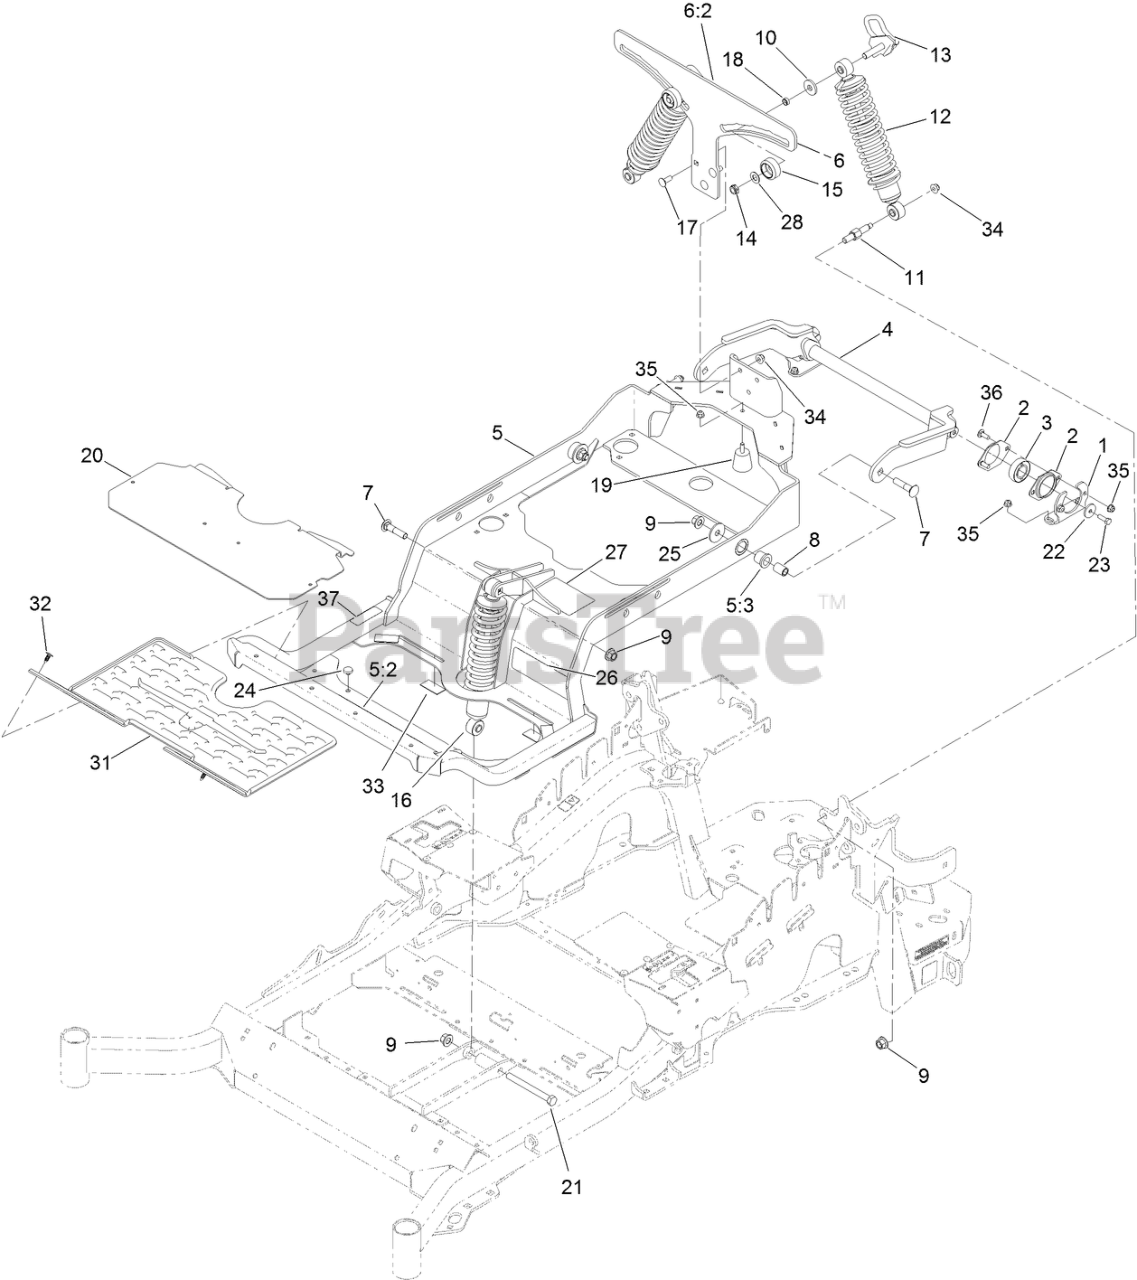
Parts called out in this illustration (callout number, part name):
1	BRACKET-BEARING
2	HOUSING-BEARING, FLANGE
3	BEARING
4	ARM-TRAILING
5	SUBFRAME ASM
5:2	DECAL-DANGER
5:3	BUSHING-FLANGE
6	BRACKET-MOUNTING
6:2	DECAL-ADJUSTMENT, RIDE
7	SCREW-CARR
8	SPACER-ALUMINUM
9	NUT-LOCK
10	WASHER-PLASTIC
11	BOLT-SHOULDER
12	SHOCK/SPRING ASM
13	CAM LOCK ASM
14	NUT-HEX
15	KNOB-LOCK, CAM
16	SHOCK ASM-FRONT
16	SHOCK/SPRING ASM
17	SCREW-CARR
18	BEARING-SLEEVE
19	BUMPER-RUBBER
20	FLOORPAN
21	SCREW-HH
22	WASHER-FLAT
23	SCREW-HH, THREAD LOCKING
24	BUMPER
25	WASHER-THRUST
26	DECAL-MYRIDE
27	DECAL-SERVICE AID
28	WASHER-ADJUSTING
31	FLOORMAT-MYRIDE
32	PLUG-PLASTIC
33	PAD-RUBBER
34	NUT-HF, NI
35	NUT-HF, NI
36	BOLT-CARR
37	DECAL-BRAKE, PARKING
